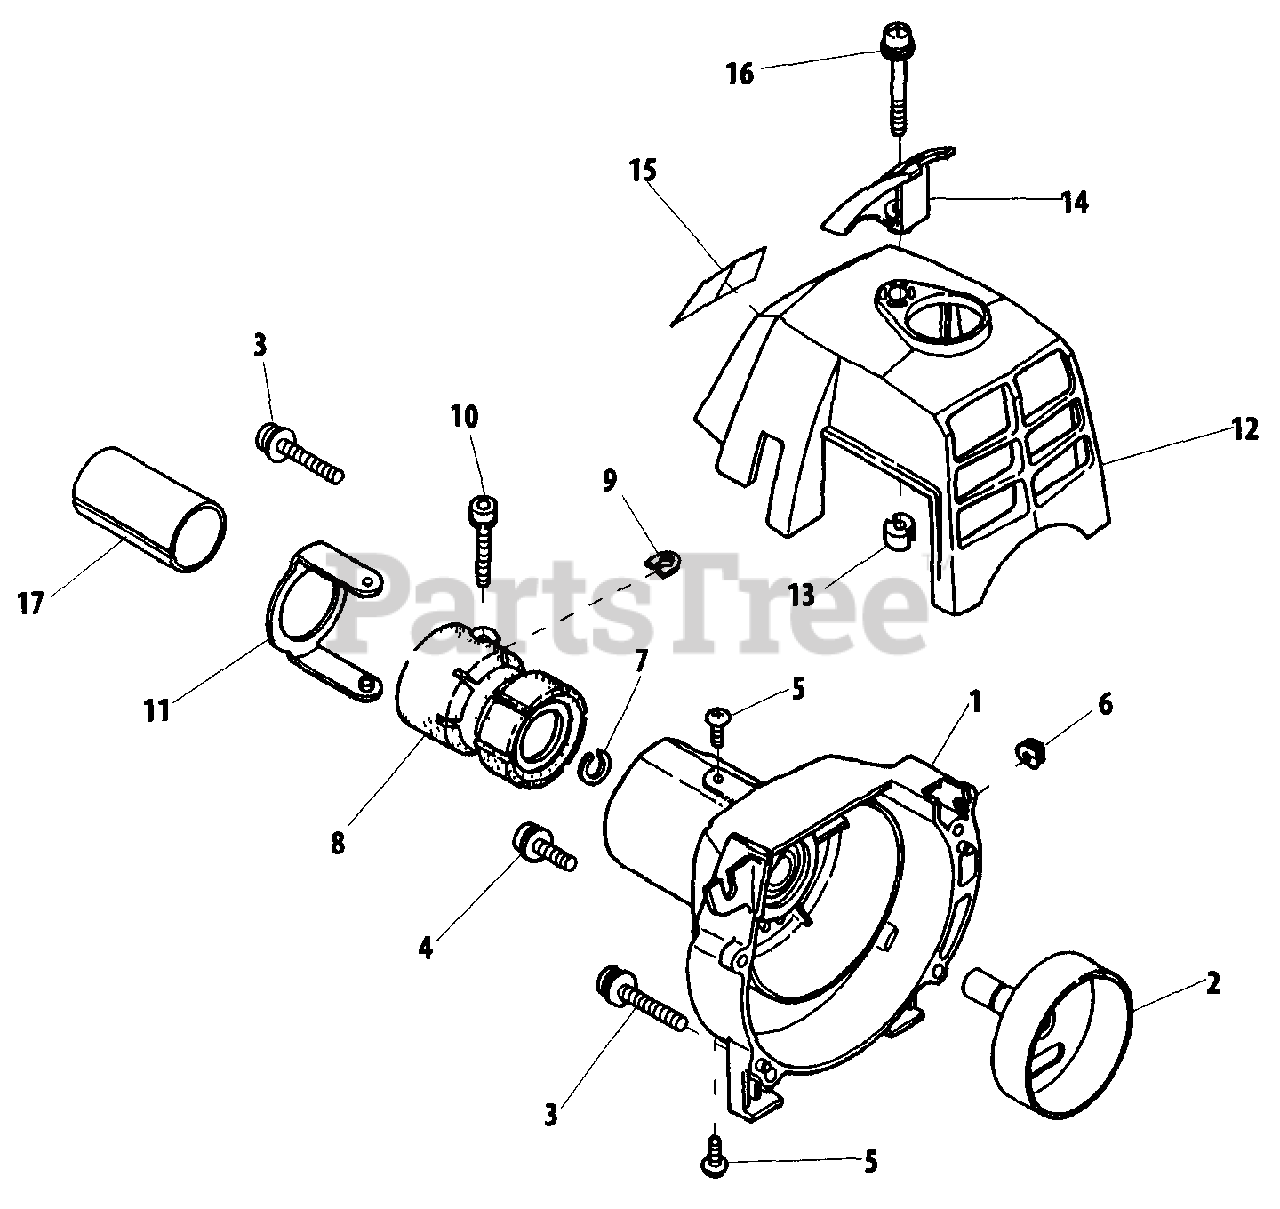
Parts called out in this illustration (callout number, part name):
1	COVER, FAN
2	DRUM, CLUTCH
3	SCREW M5×30
4	SCREW M5×16
5	SCREW, ADHESIVE M4×8
6	GROMMET, LEAD
7	RING, SNAP Ø12
8	JOINT
9	D-WASHER
10	BOLT M5×22
11	STOPPER
12	COVER, ENGINE
13	INSULATOR
14	PROTECTOR
15	NAME LABEL
16	SCREW
